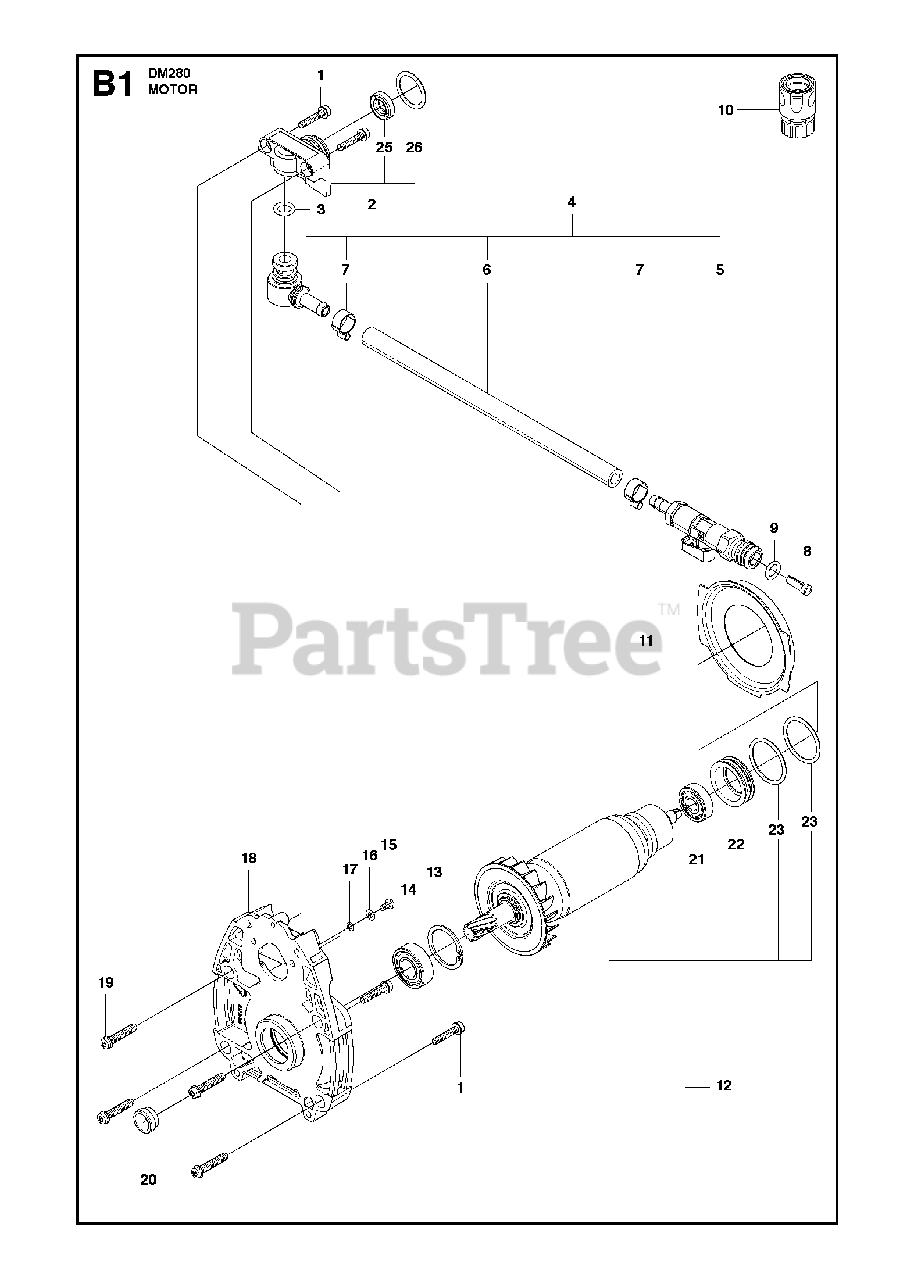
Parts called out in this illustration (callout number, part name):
1	SCREW IHSCFM
10	COUPLERUS, CANADA
14	BALL BEARING
